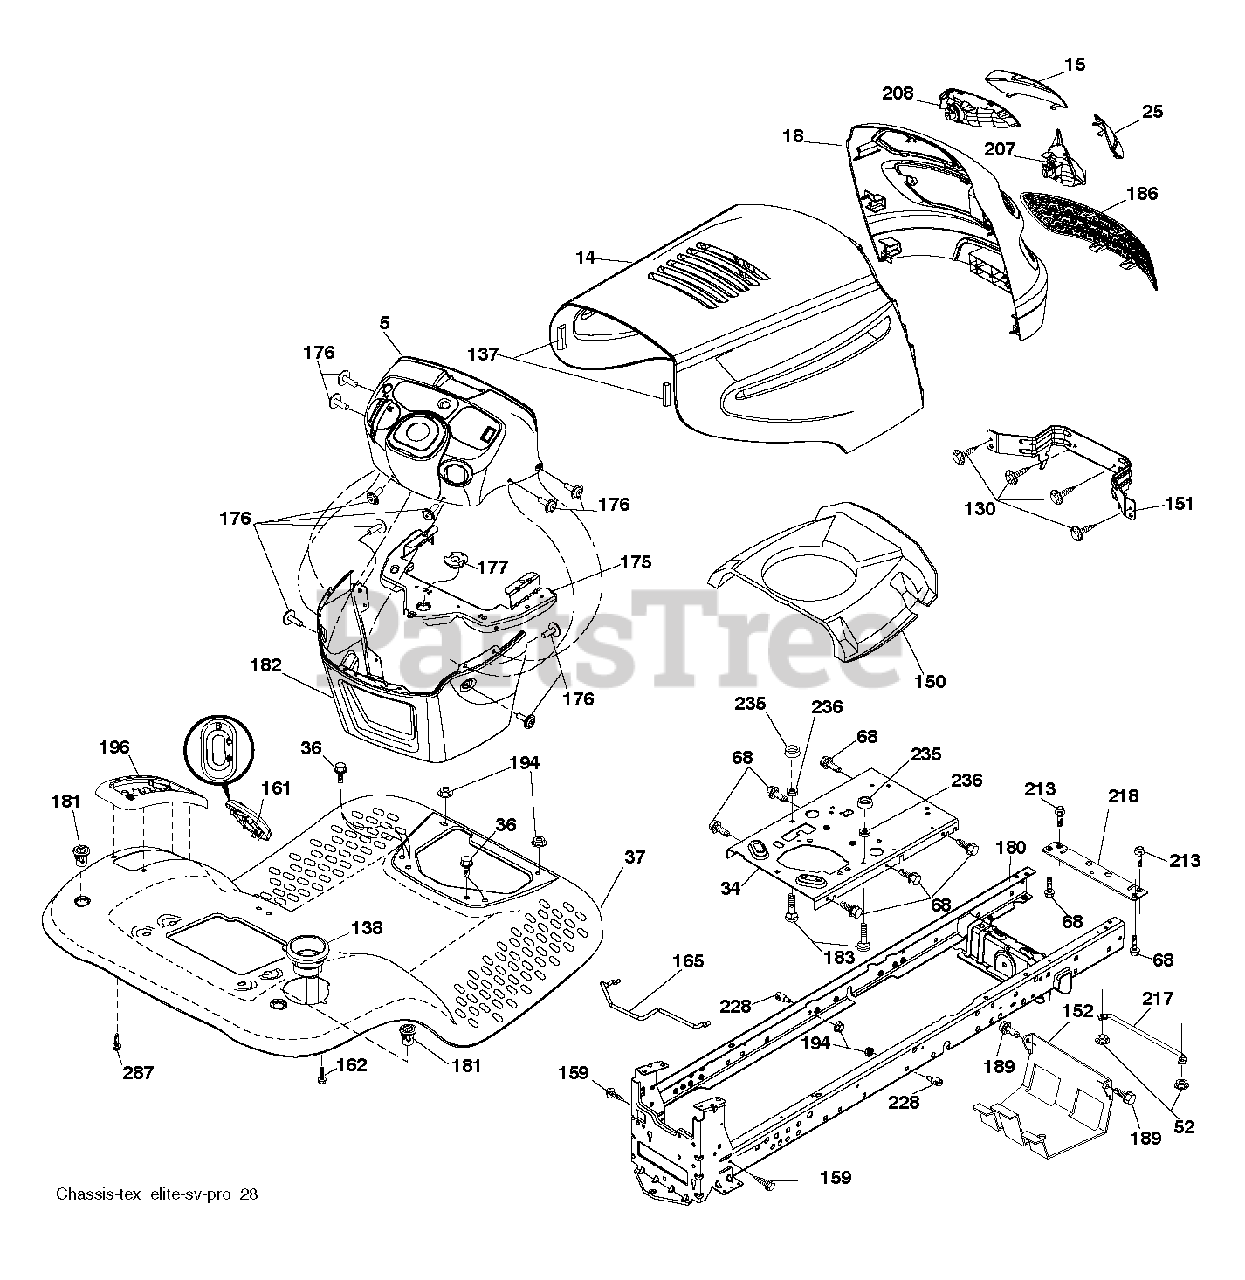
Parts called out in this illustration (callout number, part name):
36	SCREW 5/16"
52	LOCKNUT
130	SCREW.#10 X 0.750.BOS THREAD
137	BUMPER.HOOD.LARGE.1.75"
138	CUPHOLDER.TL.TEX.BLACK
151	BRACKET PIVOT
152	SHIELD BROWNING
159	SCREW, 3/8-16X3/4
161	WINDOW.FUEL.LT.TEX.BLACK
162	SCREW.HI-LO.CONSOLE
165	SUPPORT.TANK.REAR.W/TE
175	CROSSMEMBER.LT
176	SCREW.#10-24X5/8.RN.QU
177	BUSHING STEERING
180	CHASSIS
181	FEND/FTRST.PCH.CPH.NFW
182	DASH.LOWER.LT.CCS
183	BOLT.5/16-18X1-1/4 FULL THD
189	SCREW
194	NUT LOCK HEX FLANGE 5/16-18
196	CONSOLE.ASM.DECKLFT.BL/RBT.TLT
207	BEZEL GRILL RH
208	BEZEL GRILL LH
213	BOLT
217	ROD.PIVOT.HOOD
218	X-PIECE.HOOD.STOP.NON/
228	STUD.FASTNER.W/ANTI-ROTATE
235	SPACER FENDER
236	NUT.CENTERLOCK.5/16-
